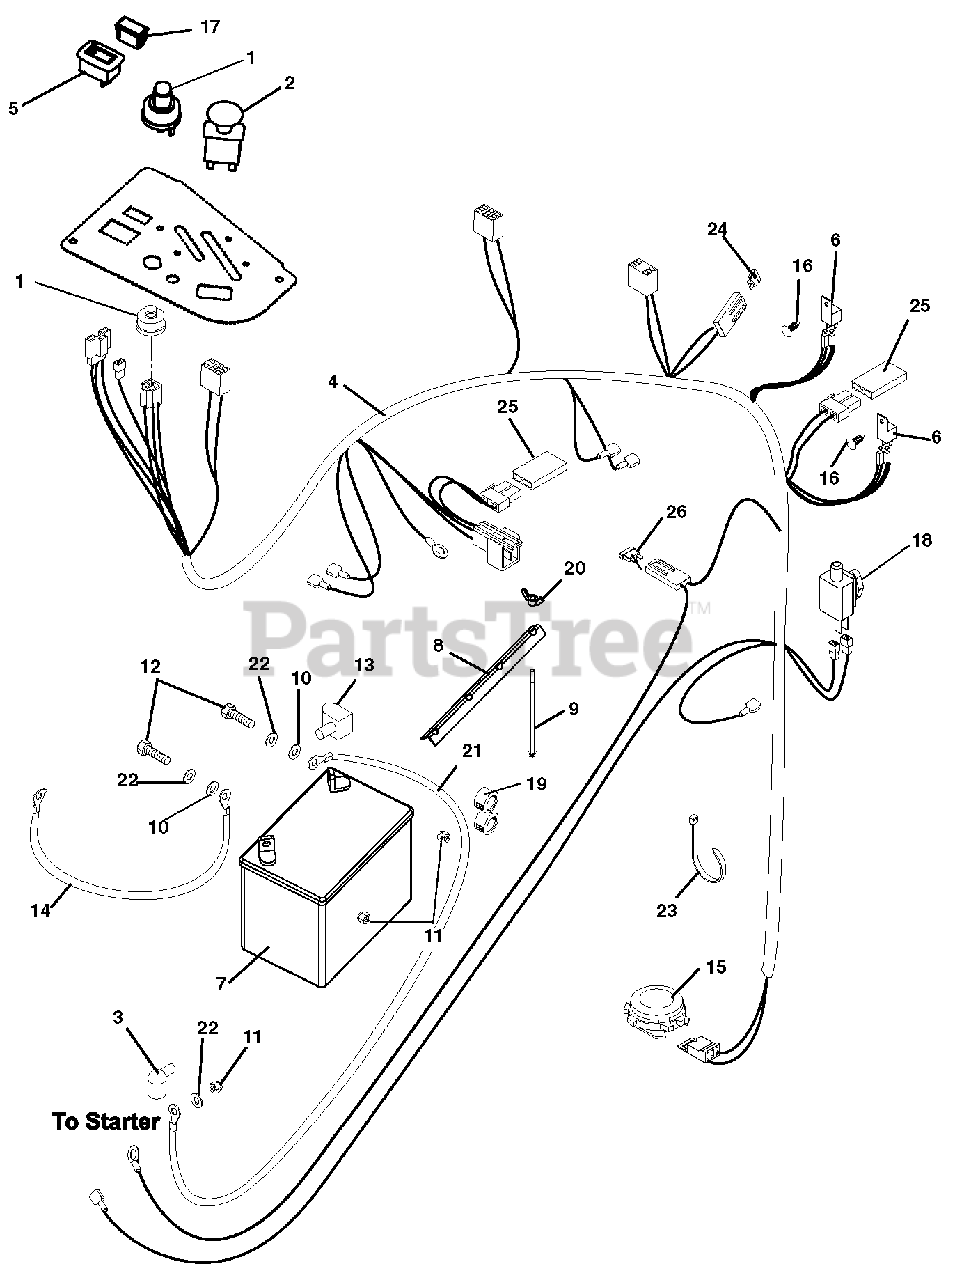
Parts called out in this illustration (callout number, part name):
1	Key, with Shield
2	Switch, Clutch
3	Boot, Eyelet Terminal
4	Harness- CZ Remote SOL.
5	Hour Meter – w/Maintenance
6	Relay, Sealed W/Diode
8	Hold Down
9	Bolt, Round Head Square Neck .25-20 x 7.50
10	Washer, Flat Steel .281 x .620 x .065
11	Nut, Hex .25-20
12	Bolt, Hex .25-20 x .75 Grade 5
13	Insulator
14	Cable, Negative Battery
15	Switch, Seat
16	Rivet, .25 Nylon Panel
17	Switch, Blank
18	Switch, Single Pole (N.O.) - Brake Switch
19	Bushing, Panel Snap .687 x .875 x .56
20	Nut, Locking Wing .25-20
21	Cable, Starter
22	Washer, Lock .25 x .062
23	Tie, Cable LG 5.50
24	Fuse 20AMP
25	Diode, Connector Shell
26	Fuse-25 AMP
